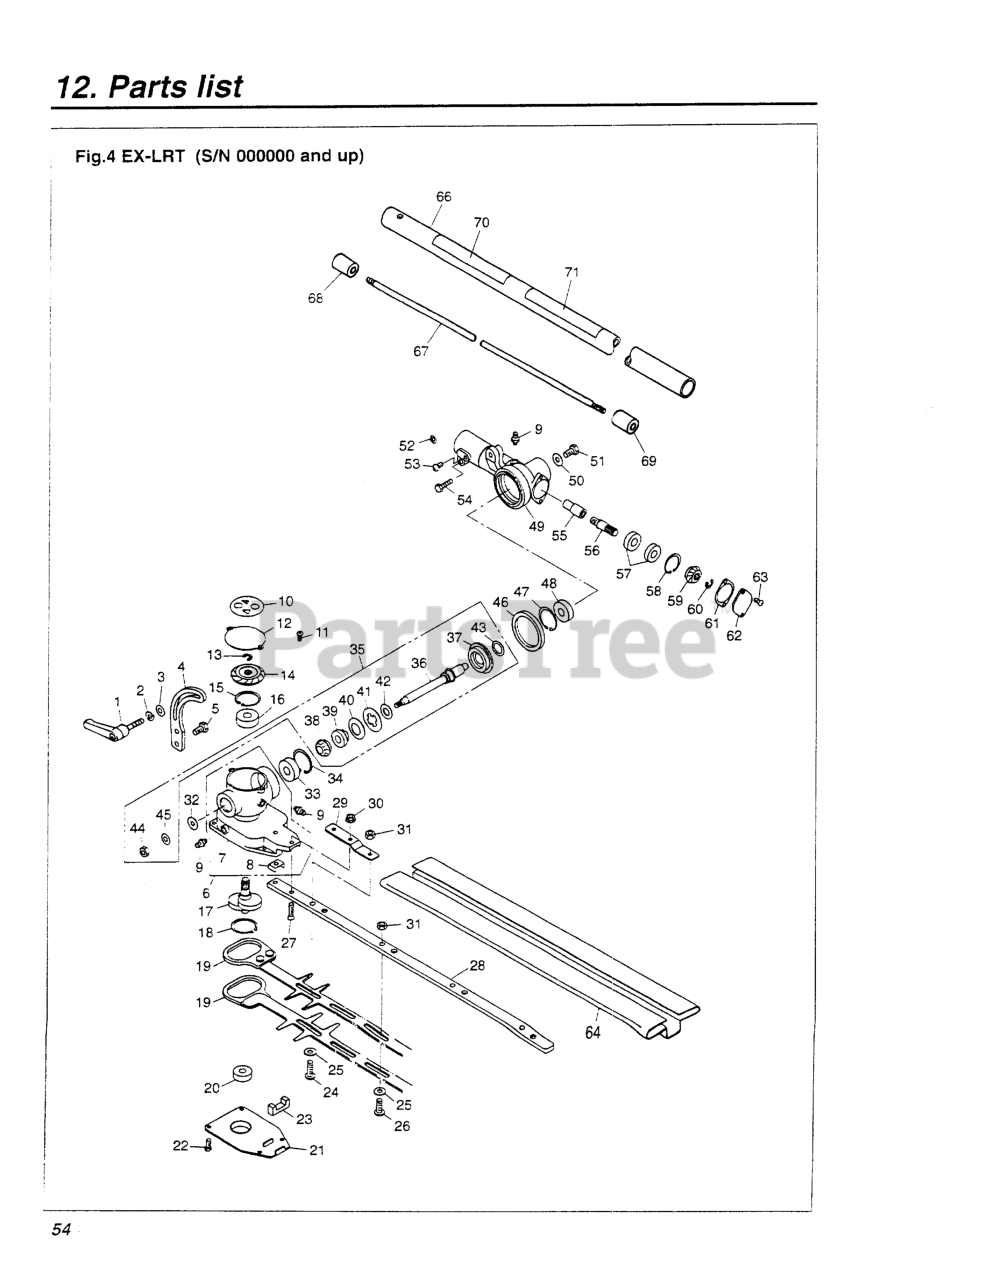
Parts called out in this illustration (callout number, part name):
2	WASHER, M6 X 15
3	WASHER, 6 X 6 X 2.0
4	ADJUSTER, ANGLE (USE-13141)
6	CASING (RPLS -13210)
7	CASING A
8	PLATE
9	FITTING, GREASE
11	SCREW, M4 X 8
13	RING, SNAP
14	GEAR, BEVEL
15	RING, SNAP, M26 X 1.2
16	BEARING
17	CRANKSHAFT
18	RING, SNAP, M28 X 1.5
19	BLADE (RPLS -13410) 18
20	BEARING
23	FELT
25	WASHER (RPLS 3873-11760)
26	SCREW
27	SCREW, M5 X 20
28	PLATE, GUIDE
29	PLATE (RPLS 6780- )
30	NUT, M5
31	NUT, M6
32	WASHER, 6X15X2.0
33	BEARING
34	RING, SNAP, M22 x 1.2
35	KIT, SHAFT (RPLS 6782-13610)
36	SHAFT
37	GEAR (B)
38	GEAR (C)
39	BOSS
40	WASHER, SPRING
41	PLATE
42	WASHER
43	WASHER
44	NUT, M6 X 5
45	WASHER, M6 X 15
46	O-RING
47	RING, SNAP, M26 X 1.2
48	BEARING
49	CASING
50	WASHER, 6 X 6 X 2.0
52	WASHER
53	BOLT, M5 X 10
54	BOLT
55	JOINT (REPLACES T3078-13810)
56	SHAFT, GEAR
57	BEARING
58	RING, SNAP, M22 x 1.2
59	GEAR, BEVEL
60	RING, SNAP
61	PACKING
62	COVER, STOPPER KIT
63	SCREW, M4 X 8
64	COVER, BLADE
66	PIPE COMPLETE
67	SHAFT
68	JOINT, SHAFT (RPLS -12240)
69	SPACER
70	PLATE, NAME (LRT-EX)
71	PLATE, CAUTION
